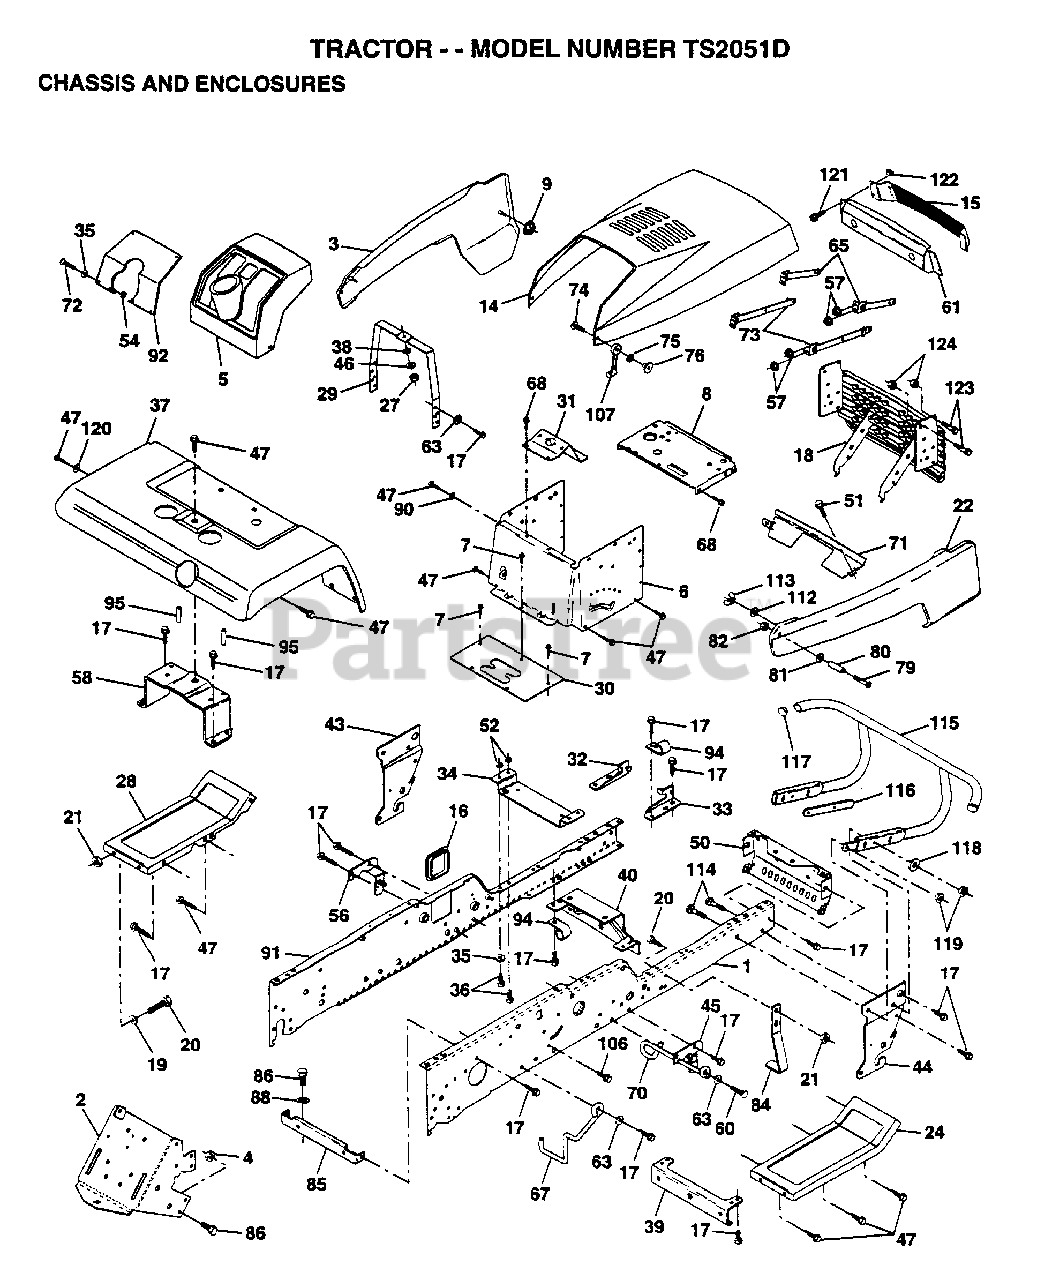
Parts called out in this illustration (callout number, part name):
2	DRAWBAR GT
4	NUT.7/16
5	DASHBOARD BLACK
6	DASH.1PC.LOWER
7	SCREW
8	SUPPORT.DASH.BTRY
9	PAL NUT LT
15	LENS LT
16	COVER ACCESS
17	SCREW
19	WASHER
20	BOLT
22	PANEL SIDE RH
26	SCREW
29	DASH.SUPT.YP/HUSQ
30	SADDLE SLKSCR VGT
31	BRAKET.SUPT.STEER
32	BRACKET ASM FRAME
33	BRACKET ASM FRAME
34	BRACKET.ENG.SUPT.
35	WASHER
36	BOLT
37	FENDER
38	LOCKWASHER
39	BRACKET.AXLE.FRT.
43	BRACKET.SUS.FT.LH
44	BRACKET.SUS.FT.RH
46	WASHER PM
47	SCREW LT
50	BRACKET.CHASSIS.
51	SCREW CRT
57	NUT HXKEP 1/4X20
58	BRKT.ASM.FENDER
60	SCREW
63	WASHER
67	GUIDE BELT TRANS
68	SCREW LT
70	GUIDE.BELT.MID.SP
71	STRAP.GRILLE.PNT.
72	SCREW
74	SCREW
75	LOCKWASHER
76	WELDNUT
79	SCREW
80	SPACER LT
81	WASHER
84	STOP.OVER.CENTER
85	BRACKET.SUPT.TRAN
86	BOLT
88	LOCKWASHER
90	LOCKWASHER
92	PLATE YP SLKSCR
94	CLIP GTV
95	NUT-PUSH YT
107	HOOD LATCH T
112	WASHER
115	BUMPER.ASM.W/PY
116	BRACKET.EXT.BUMP.
117	PLUG.PLASTIC
118	WASHER
120	WASHER HYT
122	"""J"" FASTENER LT"
124	NUT
